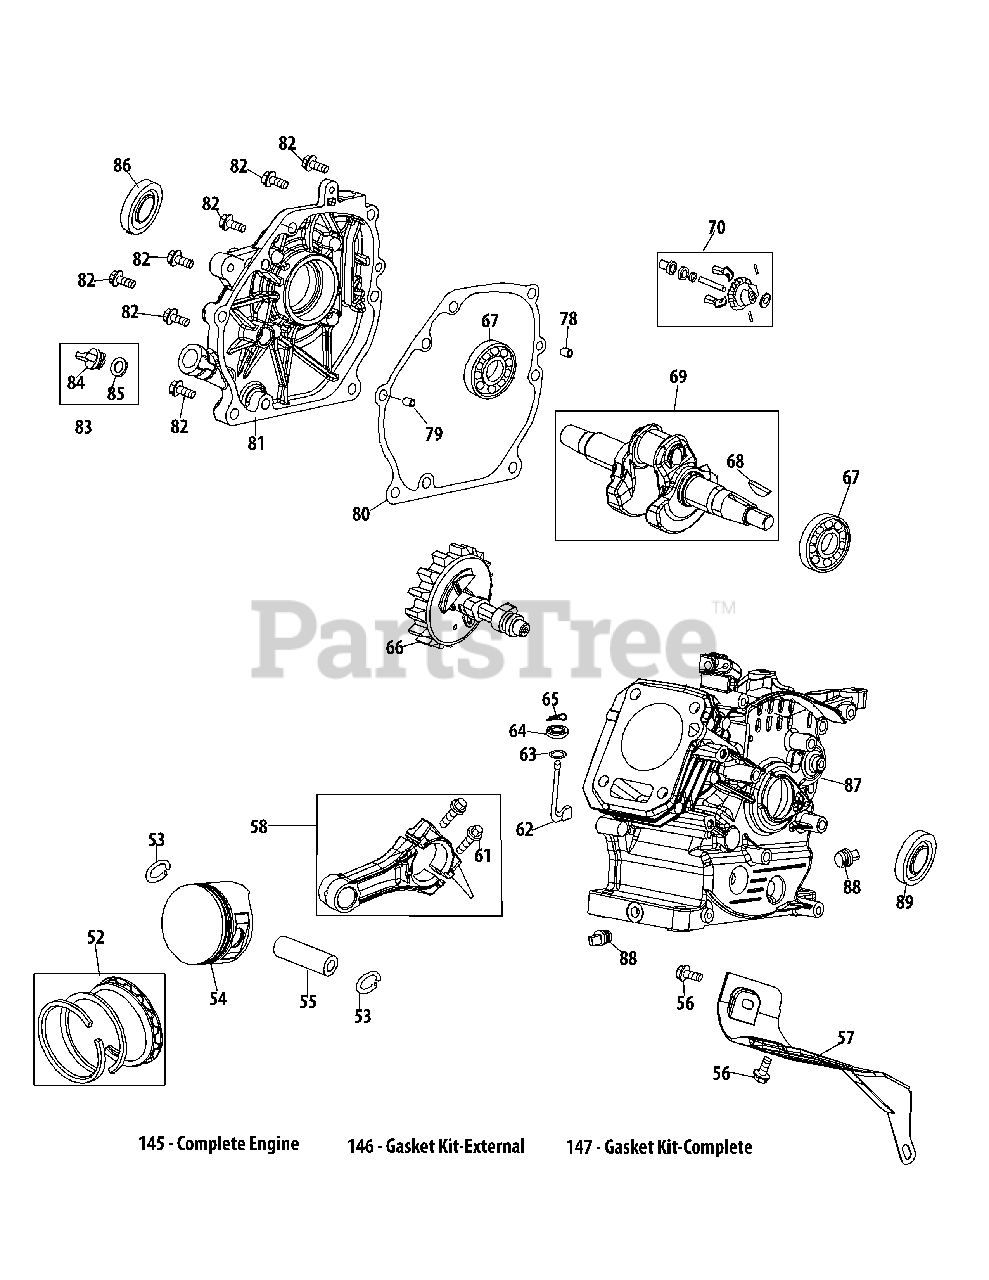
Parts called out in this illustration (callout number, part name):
52	Piston Ring Kit
53	Piston Pin Snap Ring
54	Piston
55	Piston Pin
56	Bolt M6×12
57	Air Shield
58	Connecting Rod Assembly
61	Connecting Rod Bolt
62	Governor Arm
63	Washer 5.2×1.9
64	Governor Seal
65	Cotter Pin
66	Camshaft Assembly
67	Radial Ball Bearing, 6205
68	Woodruff Key
69	Crankshaft Assembly
69	Crankshaft Service Kit
70	Governor Gear/Shaft Assembly
78	Dowel Pin 7×14
79	Dowel Pin 9×14
80	Crankcase Cover Gasket
81	Crankcase Cover
81	Crankcase Cover Kit
82	Bolt M8×32
83	Oil Fill Plug Assembly
84	Oil Plug
85	O-Ring 15.8×2.5
86	Oil Seal, 25× 41.25×6
87	Crankcase Service Kit
87	Shortblock Assembly
88	Oil Drain Plug
89	Oil Seal 25× 41.25×6
145	Complete Engine
146	Gasket Kit-External
147	Gasket Kit-Complete
